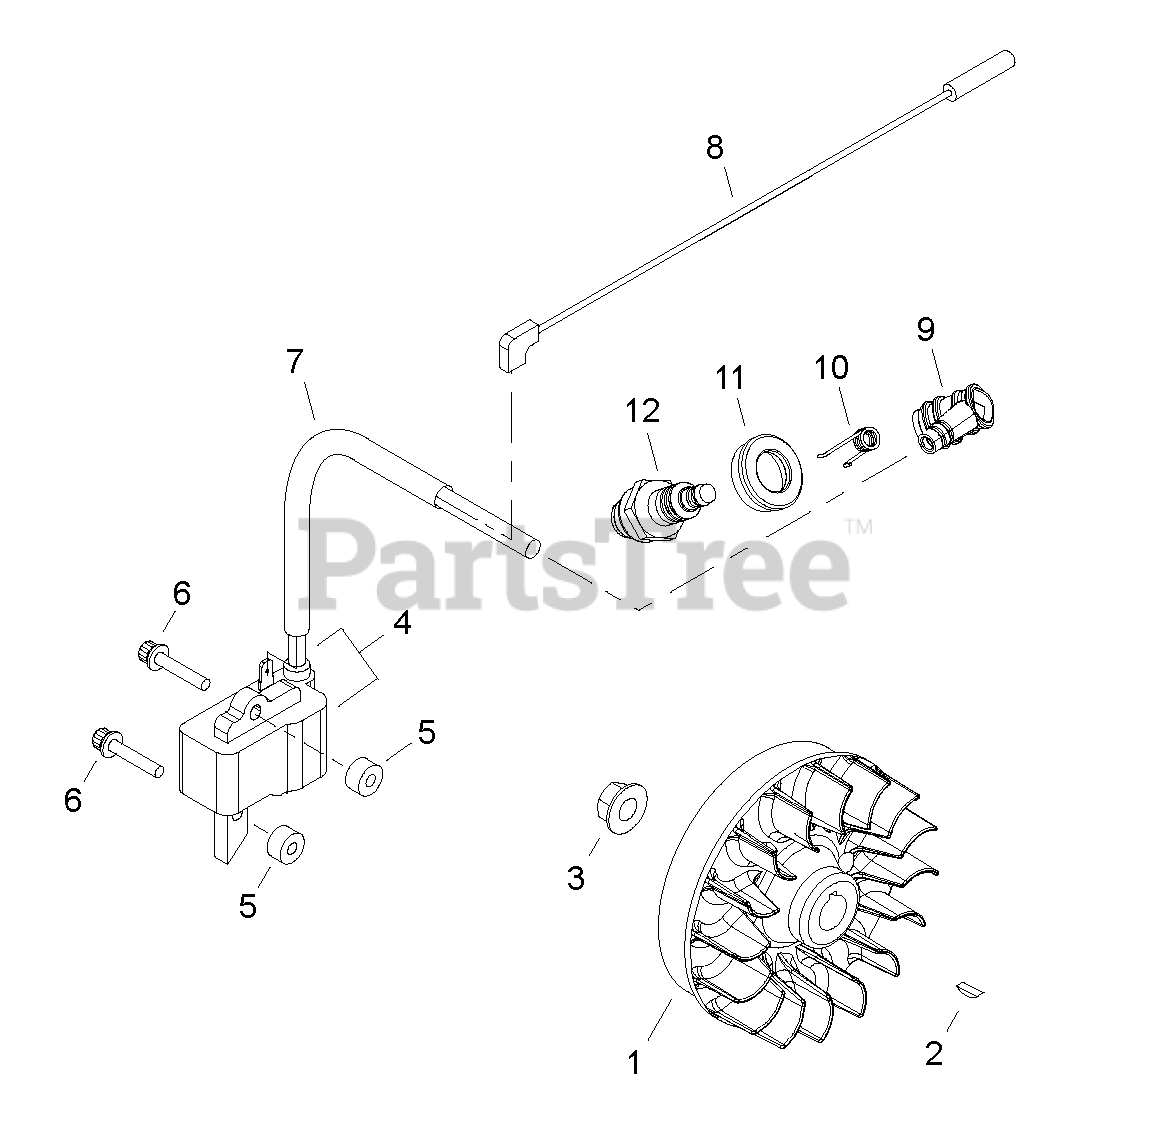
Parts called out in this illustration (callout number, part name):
1	FLYWHEEL
2	KEY, WOODRUFF 3×10
3	NUT M8
4	COIL, IGNITION
5	INSULATOR 4.2×11×6
6	BOLT, ADHESIVE M4×20
7	TUBE, IGNITION COIL
8	LEAD - IGNITION L= 215
9	CAP, SPARK PLUG
10	TERMINAL, SPARK PLUG
11	SEAL, SPARK PLUG
12	SPARK PLUG - BPMR6A
